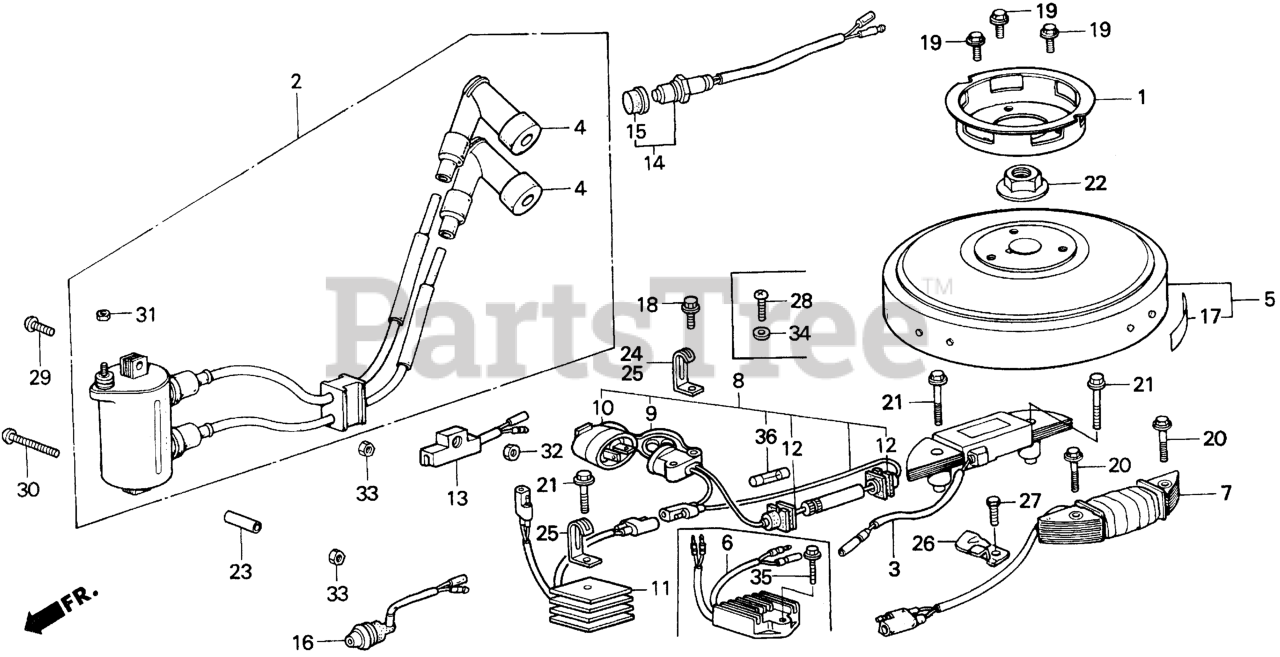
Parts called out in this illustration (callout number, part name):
1	PULLEY, STARTER
2	COIL ASSY., C.D.I. IGNITION
3	COIL ASSY., EXCITER
4	CAP ASSY., NOISE SUPPRESSOR
5	FLYWHEEL *R8* (BRIGHT RED) (NA USE ALT:31100-881-010ZC)
7	COIL ASSY., CHARGE (NOT AVAILABLE)
8	RECEPTACLE ASSY., CHARGE (NOT AVAILABLE)
9	RECEPTACLE (NOT AVAILABLE)
10	PLUG, RECEPTACLE Use up to Engine SN 1308874.
10	PLUG, RECEPTACLE
11	RECTIFIER ASSY.
13	SWITCH ASSY., NEUTRAL
14	SWITCH ASSY., ENGINE STOP
15	CAP, BUTTON (N/A: SEE ASSEMBLY)
16	LAMP ASSY., INDICATOR
17	MARK, FLYWHEEL CAUTION
19	BOLT, FLANGE (6X12)
20	BOLT, FLANGE (6X28)
21	BOLT, FLANGE (6X35)
22	NUT, SPECIAL (14MM)
23	COLLAR, DISTANCE
25	CLIP B, CORD
26	CLIP, WIRE
27	BOLT, HEX. (6X12)
27	SCREW, PAN (6X12)
28	SCREW, PAN (5X22)
29	SCREW, PAN (6X25)
30	SCREW, PAN (6X50)
31	NUT, HEX. (5MM) (NOT AVAILABLE)
32	NUT, HEX. (5MM)
33	NUT, HEX. (6MM)
34	WASHER, PLAIN (5MM)
36	FUSE A (5A)
